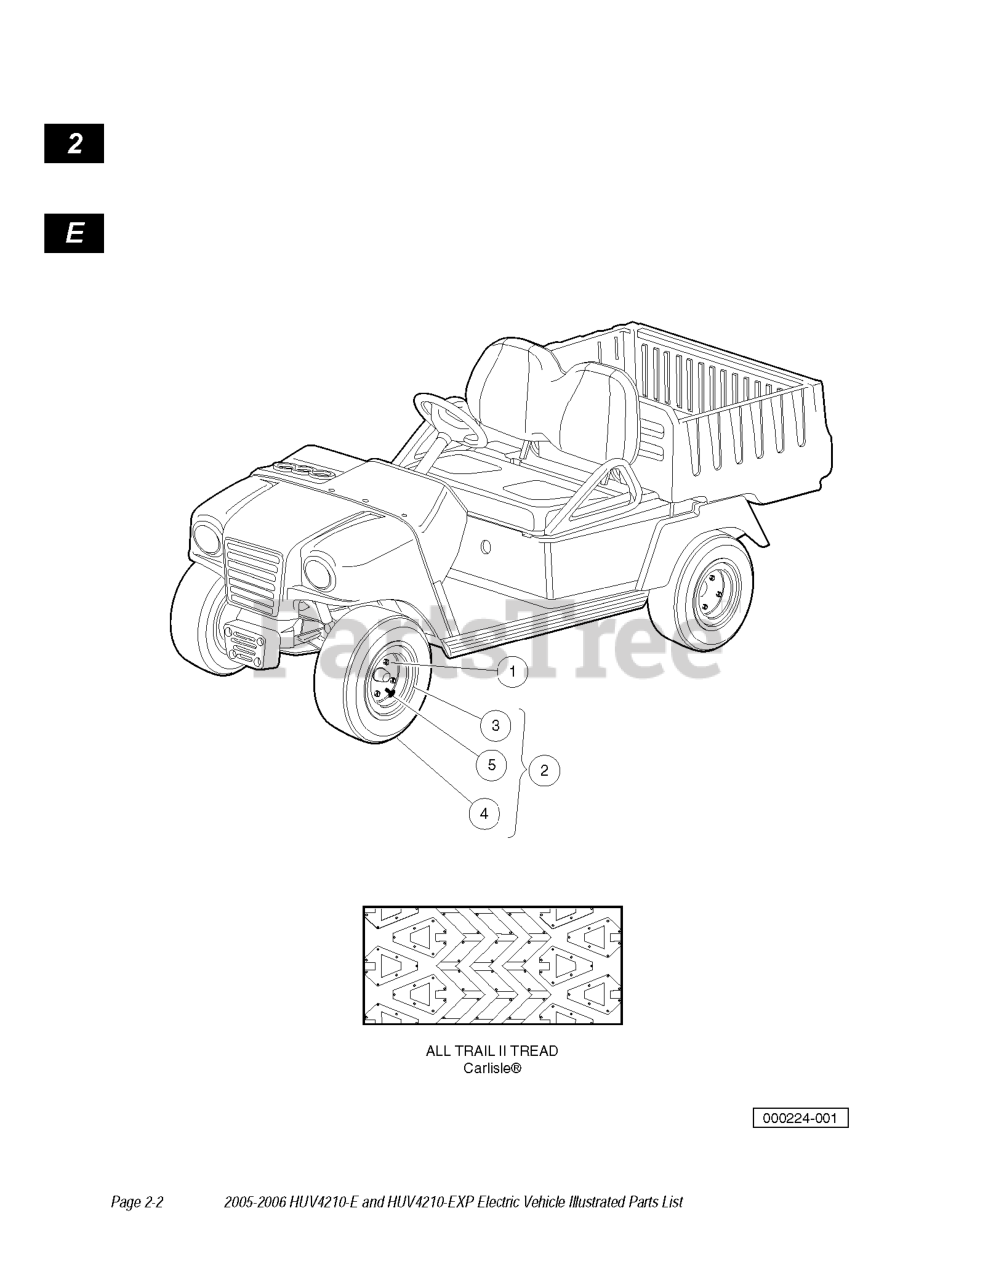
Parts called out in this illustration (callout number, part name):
1	NUT 1/2-20 LUG
2	TIRE ASM, ALL TRAIL II
3	WHEEL RIM, GRAY
4	TIRE, ALL TRAIL II
